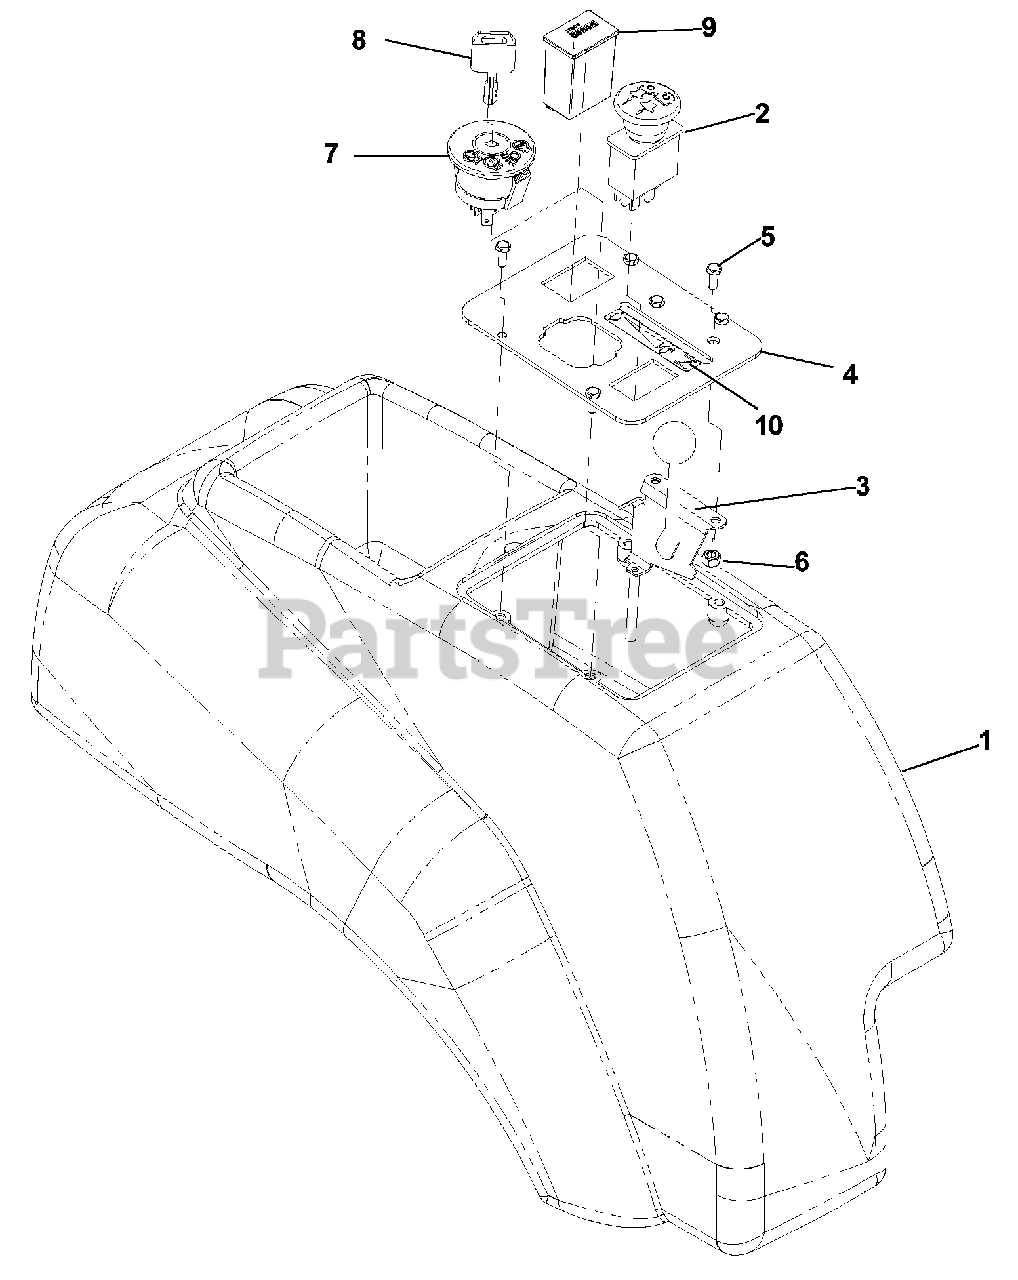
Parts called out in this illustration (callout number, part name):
2	CLUTCH SWITCH
3	THROTTLE CABLE
4	CONTROL CONSOLE
5	SCREW #10-24 X 1/2
6	NUT #10-24, NYLOC
7	IGNITION SWITCH
8	KEY
9	HOUR METER
10	DECAL, THROTTLE
